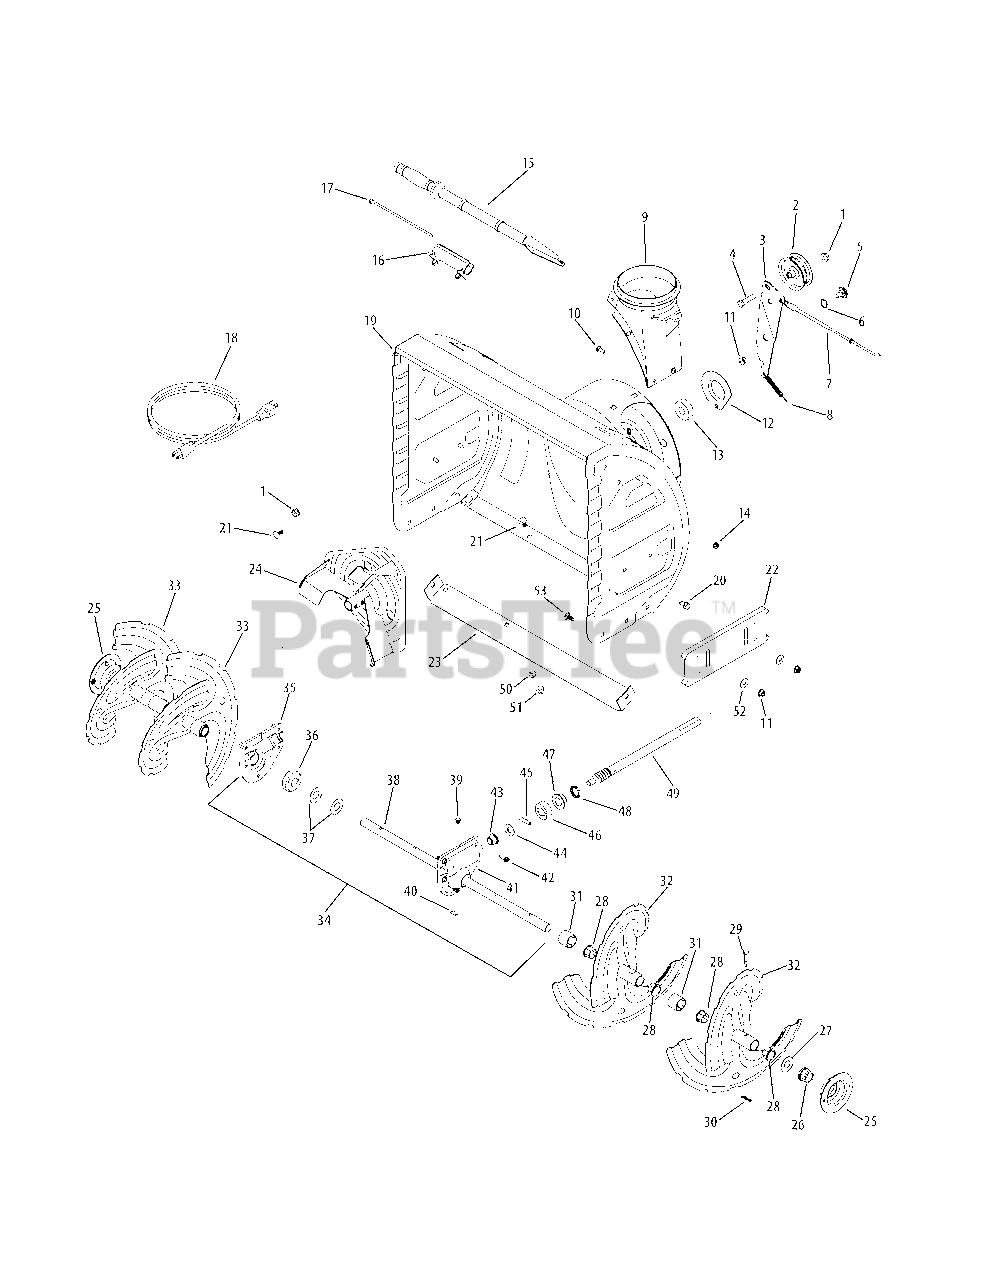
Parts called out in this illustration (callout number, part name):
1	Flange Lock Nut, 3/8-16
2	Idler Pulley
3	Auger Idler Bracket w/ Brake
4	Hex Bolt, 3/8-16 x 1.75
5	Shoulder Screw, .625 x .17 x 3/8-16
6	Wave Washer, .625 x .885 x .015
7	Clutch Cable
8	Extension Spring, .38 OD x 3.6
9	Chute Adapter, 5.0
10	Carriage Screw, 1/4-20 x .75
11	Flange Lock Nut, 5/16-18
12	Bearing Housing
13	Ball Bearing, .75 ID x 1.85 OD
14	Flange Lock Nut, 1/4-20
15	Cleanout Tool
16	Cleanout Tool Mount
17	Cable Tie, 3/16 x .05 x 7.4
18	Extension Cord, 3-Prong
19	Auger Housing, 26"
20	Hex Washer Screw, 5/16-18 x .750
21	Carriage Bolt, 5/16-18 x .750
22	Deluxe Polymer Skid Shoe
23	Stainless Steel Shave Plate, 26"
24	Impeller Assembly
25	Bearing Housing
26	Hex Flange Bearing
27	Flat Washer, .76 x 1.49 x .06
28	Flange Bushing .800 ID x .910 OD
30	Bow-Tie Cotter Pin
31	Spacer, 1.25 OD x .75 ID x 1.00
32	Spiral Assembly, LH
33	Spiral Assembly, RH
34	Gearbox Assembly, 26"
35	Housing Assembly, RH
36	Worm Gear, 2OT
37	Flat Washer, .760 ID x 1.50 OD
38	Auger Axle, 26"
39	Plug, 1/4 x .437
40	Hi-Pro Key, 3/16 x 5/8
41	Housing Assembly, LH
42	Hex Washer Screw, 1/4-20 x .750
43	Flng. Bearing, .50 ID x .75 OD x .59
44	Flat Washer, .51 x 1.12 x .06
45	Dowel Pin, .25 OD x 1.25
46	Thrust Collar, .756 ID x .600
47	Flng. Bearing, .75 ID x 1.0 OD x.59
48	Oil Seal, .75 x 1.131 x .188
49	Worm Shaft, .75 OD
50	Bell Washer, .340 x .872 x .060
51	Hex Nut, 5/16-18
52	Flat Washer, .349 x .879 x .063
53	Carriage Screw, 5/16-18 x 1.00
